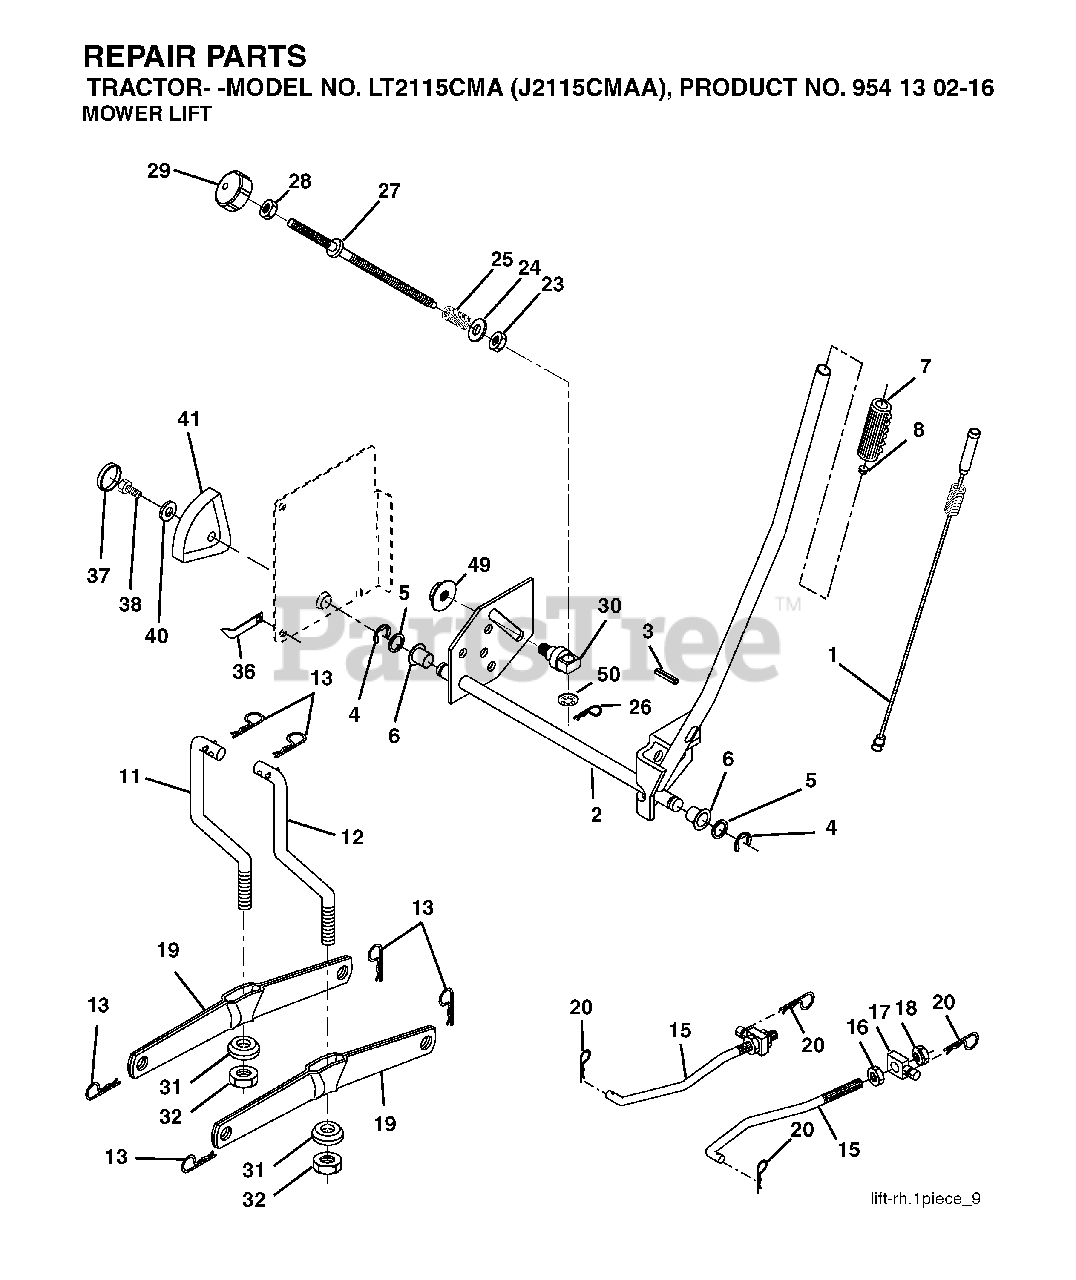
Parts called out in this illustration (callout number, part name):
1	WIRE ASM INNER W/ PLUNGER LT
2	SHAFT ASM R HANDLE
3	PIN GROOVE
4	RETAINING RING LT
6	BEARING.NYLON
7	GRIP HANDLE
8	PLUNGER BUT KIT
11	LINK
12	LINK
13	RETAINER-SPRNG RB
15	LINK.SUSPENSION.FRONT
16	NUT
18	NUT
19	ARM.REAR.SUSPENSION
20	SPRING RETAINER
25	SPRING**
26	RETAINER CLIP
27	ROD ADJ LIFT
28	NUT
29	KNOB INF 3/8-16
31	BEARING.PIVOT.LIFT
32	NUT CROWNLOCK 3/8-24
36	POINTER, HEIGHT INDICATOR
37	PLUG,HOLE
38	SCREW 5/16-18X1
41	HEIGHT INDICATOR
49	NUT
50	NUT PUSH M
